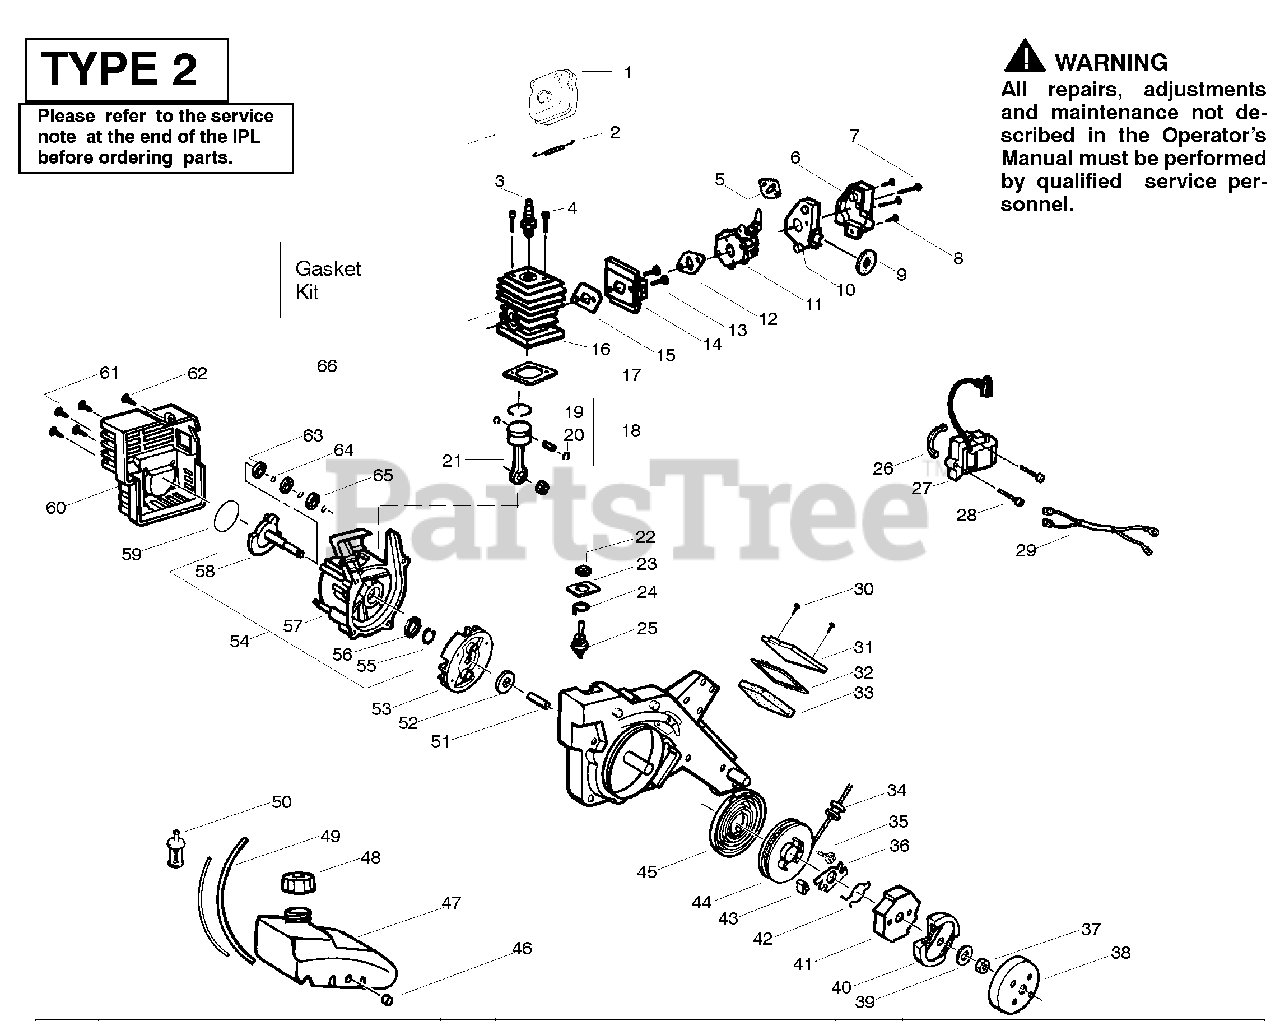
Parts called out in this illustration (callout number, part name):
1	Kit-Muffler
2	Spring-Muffler
3	Plug-Spark (RCJ-6Y)
5	Gasket-Carb/Bracket(kit)
6	Cover-Air Box
9	Seal-Foam (kit)
11	Kit-Carb. (WT-308)
11	Kit-Carb. (Wt-630)
12	Gasket-Carb.(kit)
14	Adapter-Carb.
15	Gasket-Cyl./Carb. (kit)
16	Kit-Cylinder
17	Gasket-Cyl. (kit)
18	Kit-Piston
20	Ring-Piston
21	Kit-Conn. Rod Assy.
22	Boot-Switch w/nut
23	Plate-Switch Indicator
24	Terminal-Grounding
25	Assy-Gound Switch
26	Spacer-Module
27	Module-Ignition
29	Assy-Switch Wire
31	Cover-Air Filter
32	Gasket-Cover (kit)
33	Foam-Air Filter
39	Washer-Flywheel
42	Wire-Starter Dog
44	Kit-Starter Pulley
45	Spring-Starter
46	Isolator-Crankcase
47	Assy-Fuel Tank
48	Assy-Fuel Cap
49	Kit-Fuel Line
50	Assy-Fuel Pick-up
51	Spacer-Flywheel
53	Assy-Flywheel
54	Assy-C/shaft & C/case
55	Retainer-C'shaft
56	Seal-Crankcase
57	Assy-C'case
58	Assy-Crankshaft
59	O-ring-c'case/shrd (kit)
61	Screw
63	Bearing-Inner
64	Retainer-C'case
65	Bearing-Outer
66	Kit Gasket
